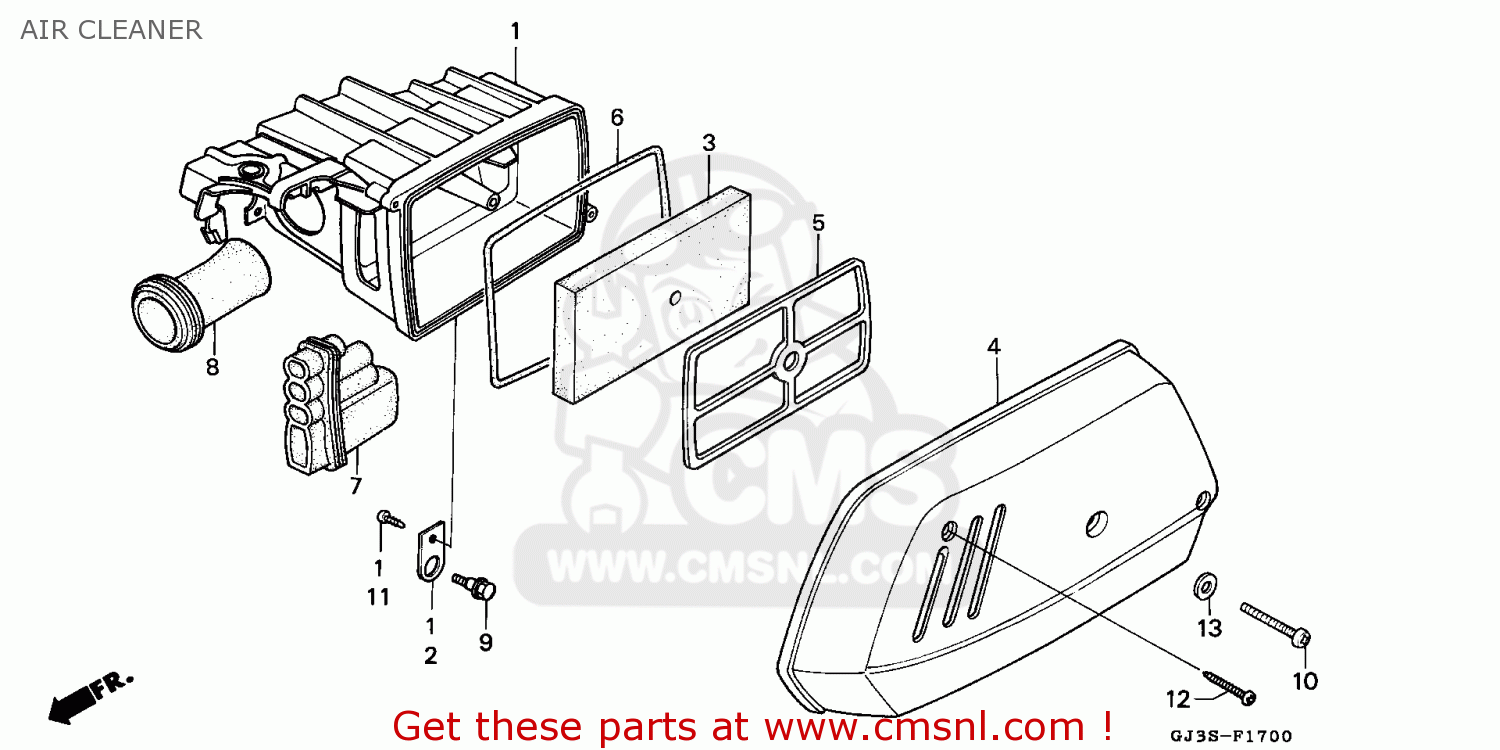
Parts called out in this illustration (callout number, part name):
1	CASE COMP. AIR/C
2	STAY AIR/C
3	ELEMENT,AIR CLEAN
4	COVER AIR/C
5	HOLDER ELEMENT
6	SEAL,AIR/C COVER
7	DUCT,AIR/C CASE
8	TUBE AIR/C CONN.
9	BOLT,SPECIAL,6MM
10	SCREW,PAN.5X35
11	SCREW TAPP 4X16
12	SCREW,TAPPING4X25
13	WASHER,PLAIN,5MM
